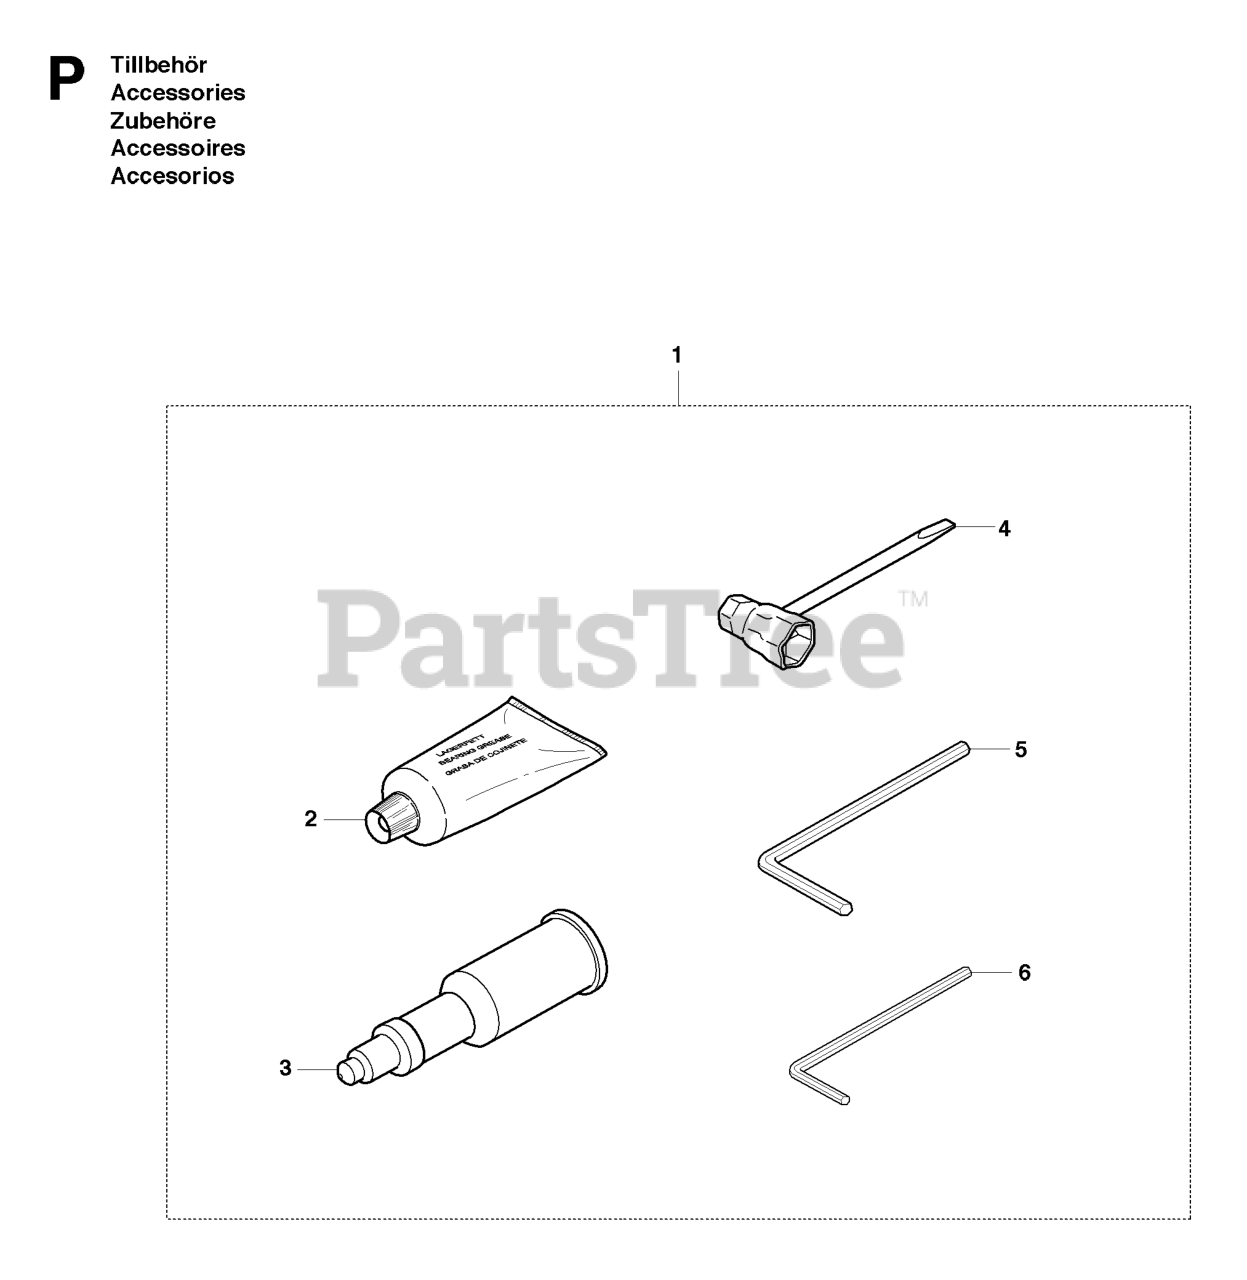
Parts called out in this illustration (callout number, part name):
1	TOOL KIT
2	GREASE
3	Grease Gun
4	COMBI TOOL
